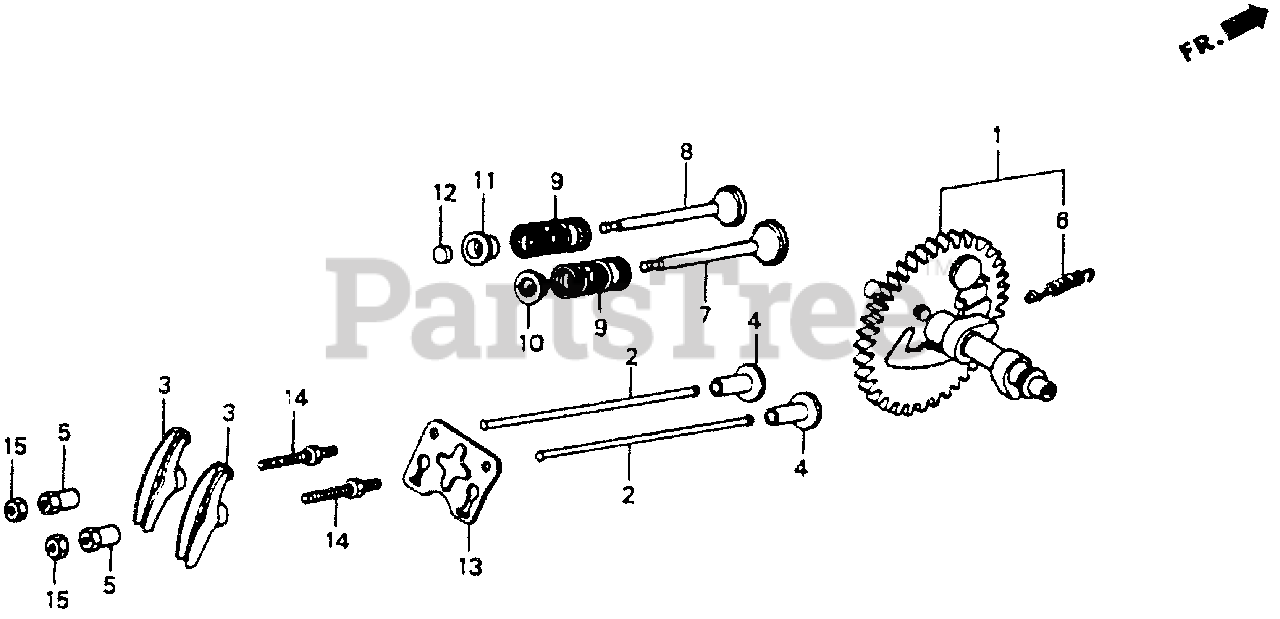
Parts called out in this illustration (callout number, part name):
1	CAMSHAFT ASSY.
2	ROD, PUSH
3	ARM, VALVE ROCKER
4	LIFTER, VALVE
5	PIVOT, ROCKER ARM
6	SPRING, WEIGHT RETURN
7	VALVE, IN.
8	VALVE, EX.
8	VALVE, EX. (STELITE)
9	SPRING, VALVE
10	RETAINER, IN. VALVE SPRING
11	RETAINER, EX. VALVE SPRING
12	ROTATOR, VALVE
13	PLATE, PUSH ROD GUIDE
14	BOLT, PIVOT
14	BOLT, PIVOT (8MM)
15	NUT, PIVOT ADJUSTING
